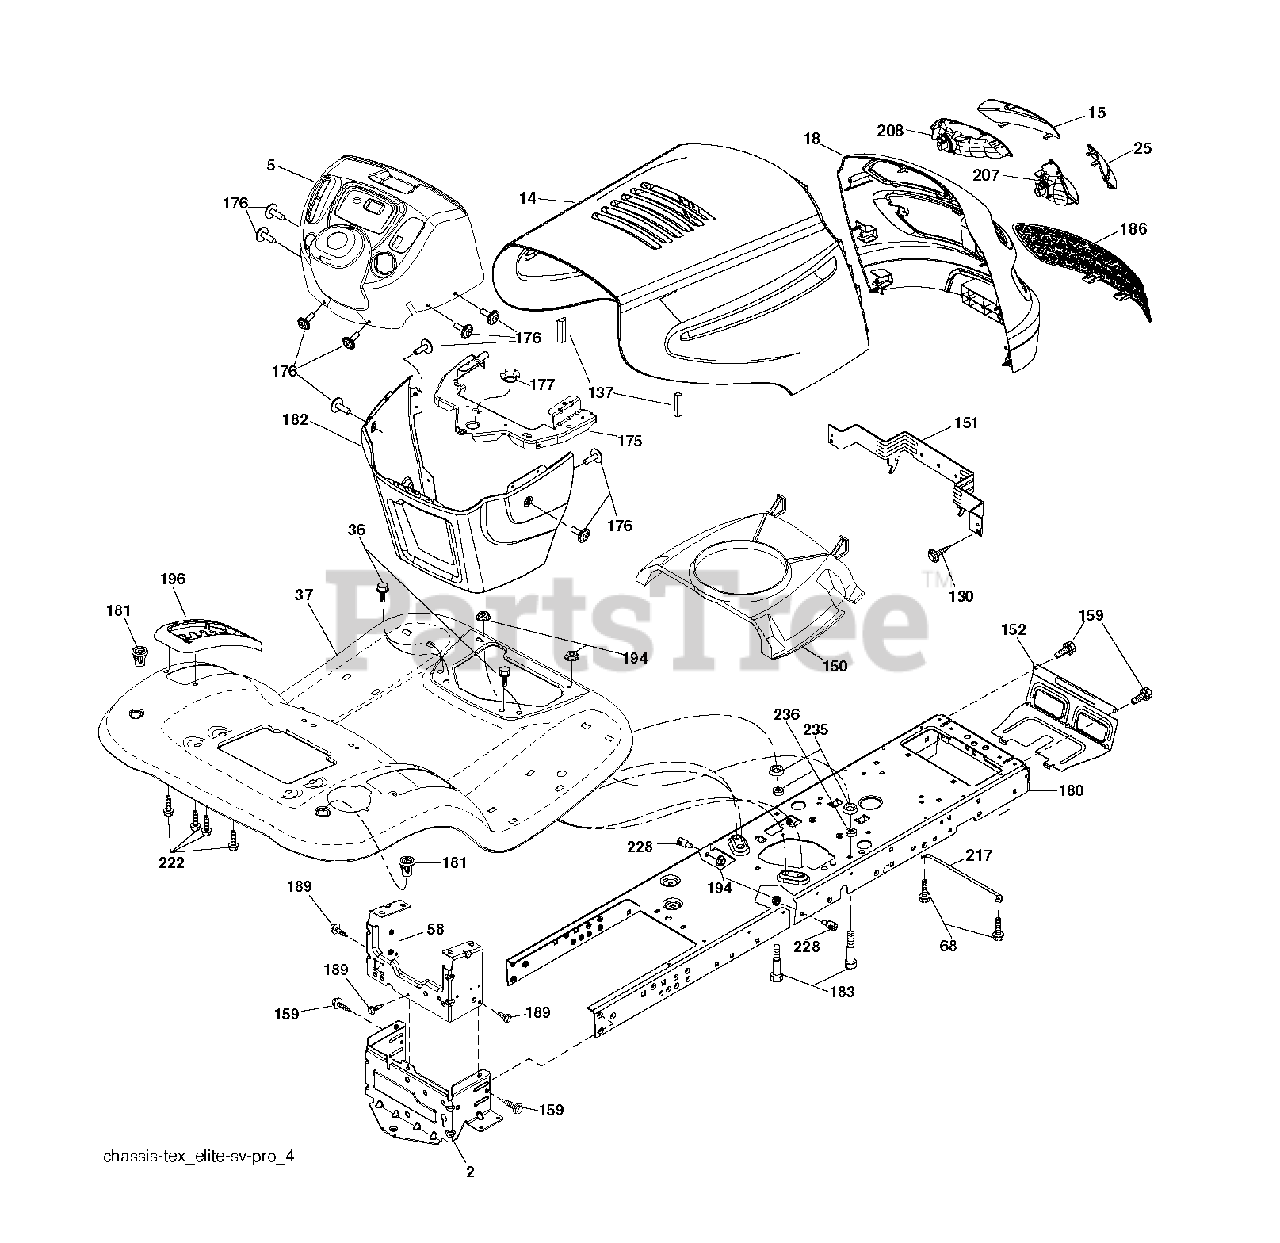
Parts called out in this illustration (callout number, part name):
2	DRAWBAR.LOWER.2PC.18/22
36	SCREW 3/8-16X3/4
58	DRAWBAR UPPER 2PC SMALL FENDER
130	SCREW
137	BUMPER.HOOD.LARGE.1.75"
151	BRACKET PIVOT
152	SHIELD.BROWNING/DEBRIS
159	SCREW, 3/8-16X3/4
175	CROSSMEMBER.LT
176	SCREW.#10-24X5/8.RN.QU
177	BUSHING STEERING
180	CHASSIS.STAMPING.LT/GT
181	FEND/FTRST.PCH.CPH.NFW
182	DASH.LOWER.LT.CCS
183	BOLT.5/16-18X1-1/4 FULL.THREAD
189	SCREW
194	NUT LOCK HEX FLANGE 5/16-18
196	CONSOLE.ASM.DECK.LIFT.TLT.BLAC
207	BEZEL GRILL RH
208	BEZEL GRILL LH
217	ROD.PIVOT.HOOD
222	SCREW.1/4-20X5/8
228	STUD.FASTNER.W/ANTI-ROTATE
230	SHOULDER BOLT 5/16-18TT
235	SPACER FENDER
236	NUT.CENTERLOCK.5/16-
